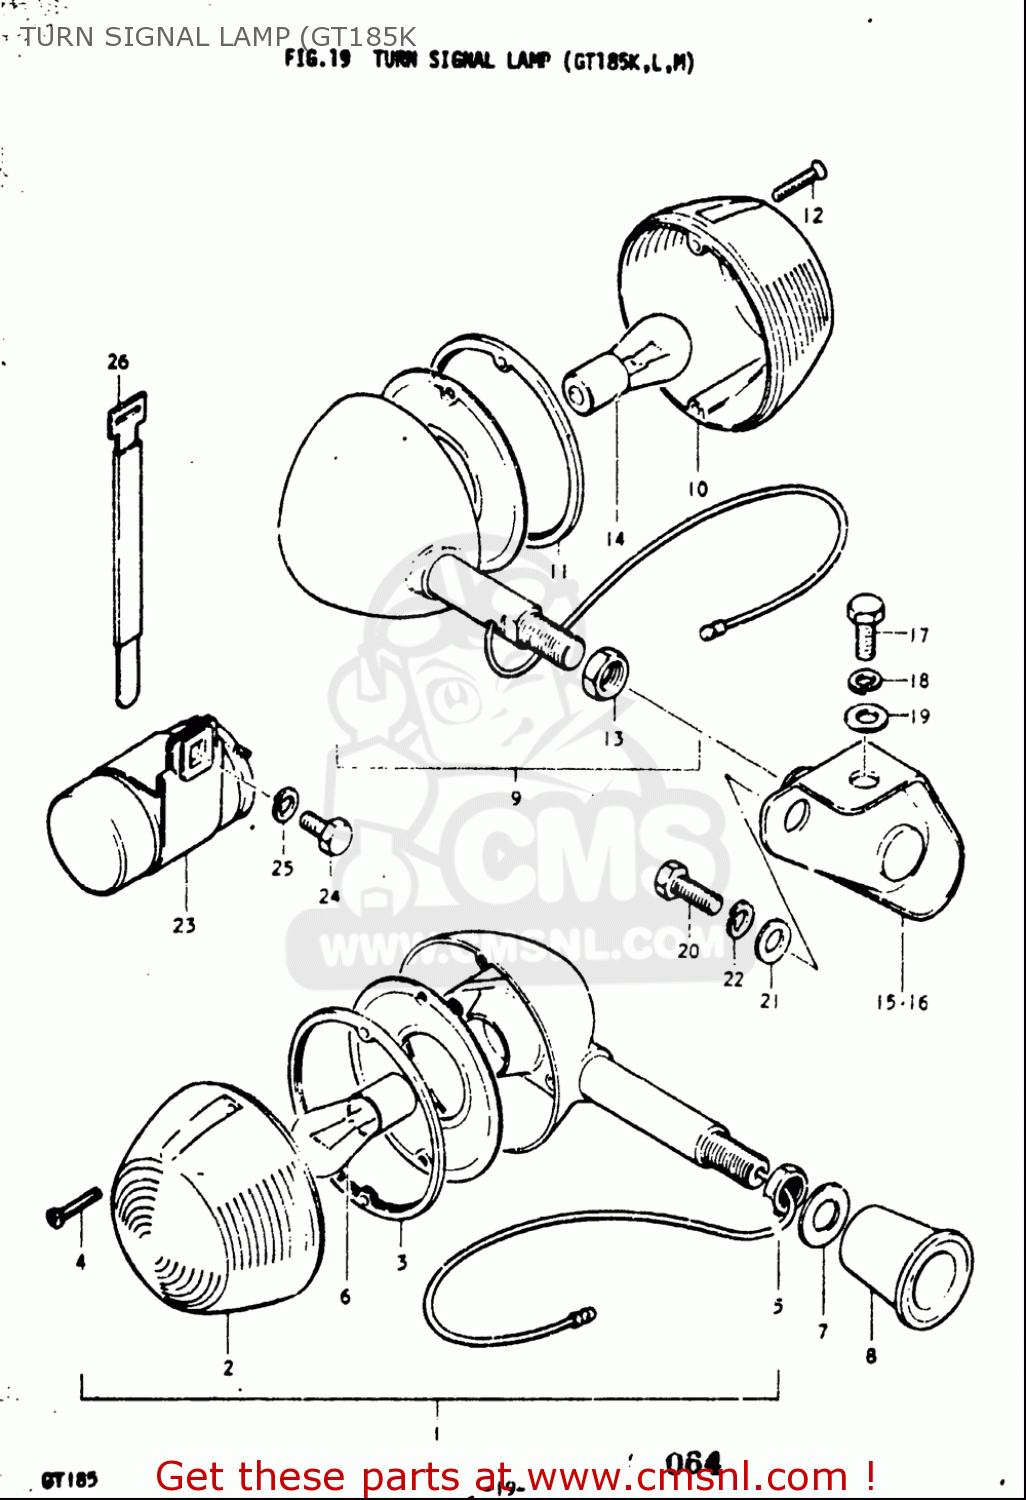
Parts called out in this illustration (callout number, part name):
1	LAMP ASSY,FR TURN SIGNAL
2	LENS,TURNSIGNAL
3	GASKET,TURNSIGNAL LENS (NAS)
4	SCREW
5	NUT
6	BULB(12V23W,STANLEY,A4577A)
7	WASHER
8	COVER,FRONT TURN SIGNAL BRACKET
9	LAMP ASSY,RR TURNSIGNAL
10	LENS,TURNSIGNAL
11	GASKET,TURNSIGNAL LENS (NAS)
12	SCREW
13	NUT
14	BULB(12V23W,STANLEY,A4577A)
17	BOLT
18	WASHER,LOCK
19	WASHER
20	BOLT
21	WASHER
22	WASHER,LOCK
23	RELAY ASSY,TURNSIGNAL
24	BOLT
25	WASHER,LOCK
26	CLAMP
